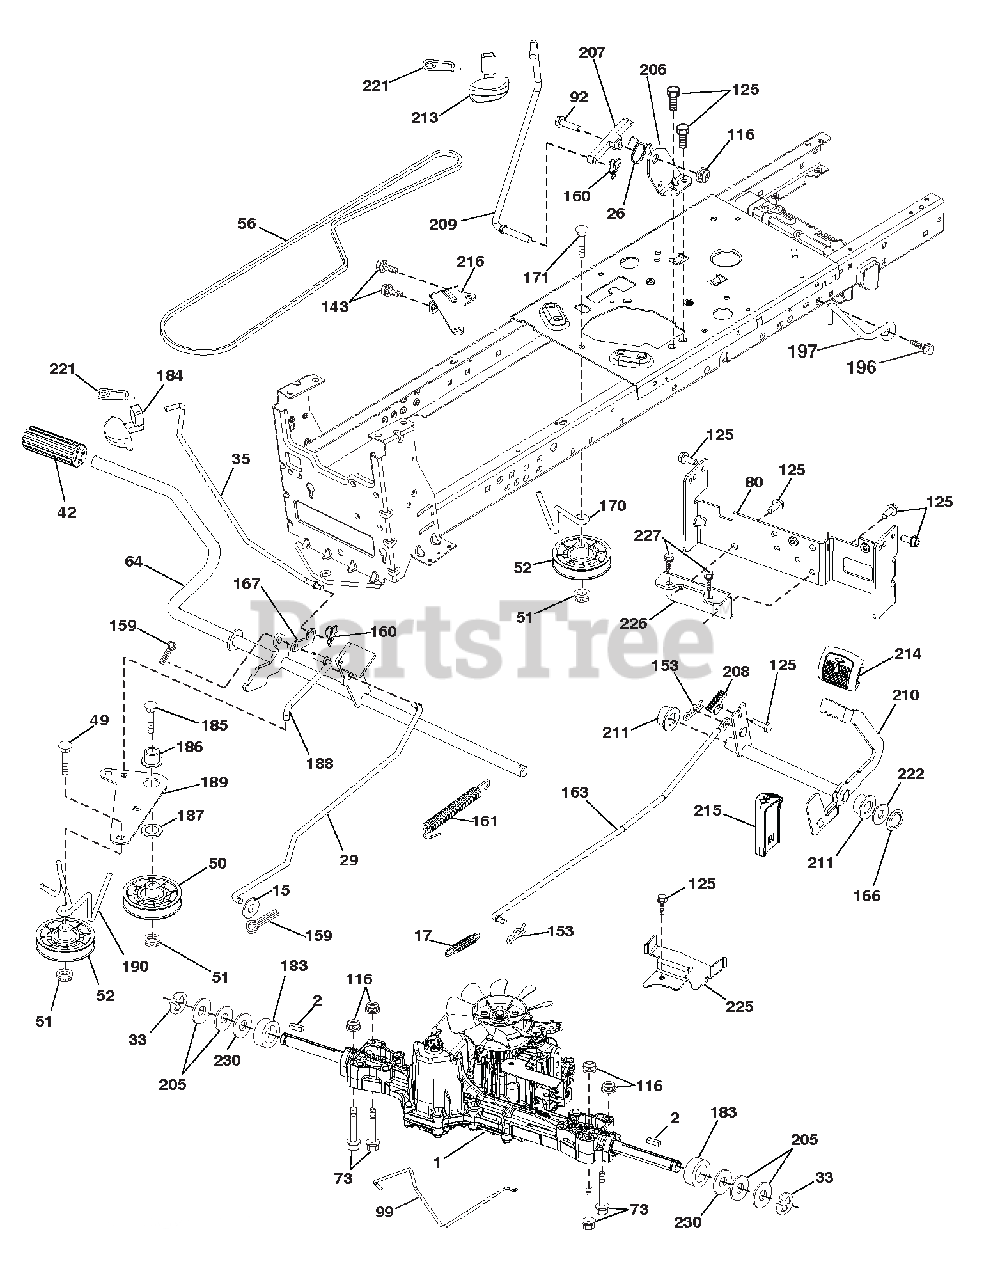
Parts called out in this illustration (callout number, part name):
2	KEY.SQUARE.2.0 X .1845/.1865
15	WASHER.13/32 X 13/16 X 16 GA.
17	SPRING.BRAKE.K46.GREEN
26	SPRING.RETURN.CRUISE
29	ROD.BRAKE.K46
33	E-RING.#5133-75
35	ROD BRAKE PARKING LT TEX
42	COVER PEDAL BLK ROUND
49	BOLT.RDHD.3/8-16UNCX1-3/4.GR5
50	IDLER.FLAT.910"OFFSET
51	Nut, Hex, Flangelock 3/8-16
52	IDLER.V-GROOVE.910"OFFSET
56	V-BELT.MOWER.92.40.42/K46
64	SHAFT ASM.PEDAL.BRK.CNTRL.PCH
73	BOLT.HEX.FLGHD.5/16-18.GR.5
80	STRAP.TORQUE.K46/18"TEX
92	Bolt, Hex Head 5/16-18 x 1-1/4
99	ROD BYPASS
116	Nut, Lock Hex Flange 5/16-18 u
125	SCREW.5/16-18X3/4.SMGML.TAP/BL
143	SCREW.THDROL.5/16-18 X 1/2TYTT
153	RETAINER SPRING
159	PIN.COTTER.1/8 X 3/4.CAD.
160	RETAINER.CLIP(M).DIA.290
161	SPRING.RETURN.CLUTCH.6.75
163	ROD CONTROL
166	NUT PUSH .625
167	LATCH.BRAKE.PARKING
170	KEEPER BELT CENTERSPAN
171	BOLT.RD.HD.SQ.NK.3/8-16UNC X 2
183	SPACER.AXLE.HYDRO/PEERLES
184	HANDLE.PARKING BRAKE.
185	BOLT.RDHD.3/8-16UNC X2-3/4 GR5
186	SPACER.RETAINER
187	WASHER.13/32 X 2 X 10 GA.
188	LINK.CLUTCH.GROUND DRIVE
189	BELLCRANK.GROUNDRIVE.NSTG/NSTL
190	KEEPER.BELLCRANK.DRIVE.GROUND
196	SCREW.3/8-16X1.SMGML.TAP/R.BLK
197	LINK.CLUTCH.ANTI-ROTATIN.1"CRK
205	WASHER.25/32 X 1-5/8 X 16GA.
206	BRACKET.MOUNT.LATCH.CRUISE
207	LATCH.CONTROL.CRUISE
208	GEAR SECTOR.CONTROL.CRUISE
209	ROD CONTROL CRUISE
210	ROCKER ASM.PEDAL CONTROL.TEXLT
211	BEARING.NYLON.BLK..629 ID.
213	KNOB CONTROL CRUISE
214	PAD PEDAL FORWARD
215	PEDAL REVERSE
216	BRACKET.PULLEY.IDLER.WTEX
221	RETAINER.SPRING.CLIP.HANDLE
222	WASHER.21/32X1-1/4.10GA.N/PLTD
225	KEEPER.BELT.TRANSAXLE.K46
226	BRACKET.MOUNT.TORQUE.K46.TLT
227	SCREW 5/16-18 X 3/4
230	WASHER.HARDEN..793 X 1.637X060
